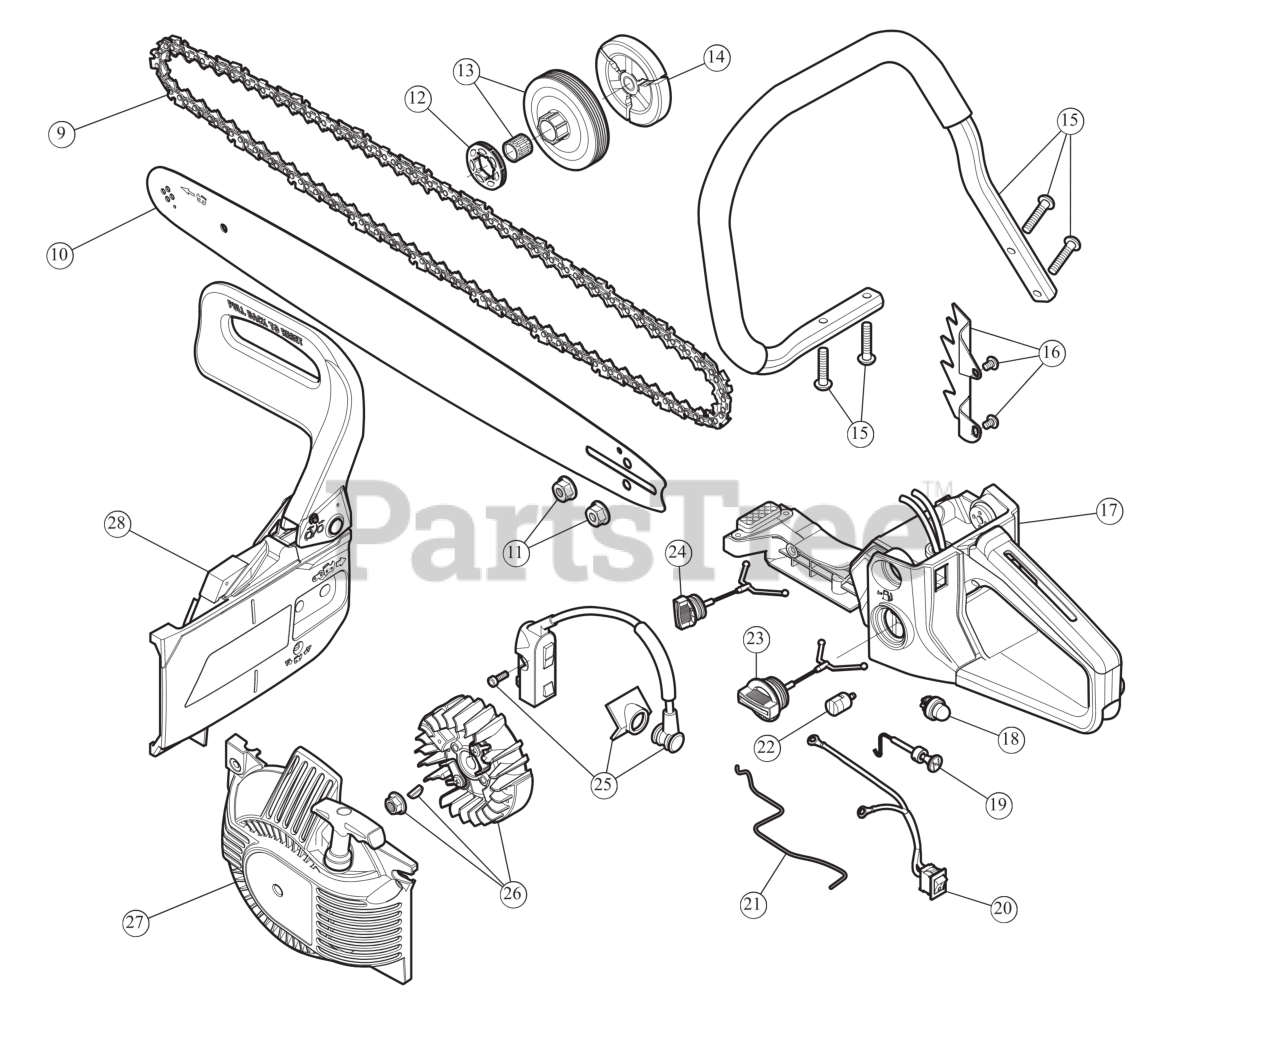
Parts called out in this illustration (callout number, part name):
9	20" CHAINSAW CHAIN
10	20" GUIDE BAR
11	BAR NUT M8
13	CLUTCH DRUM ASSEMBLY
14	CLUTCH ASSEMBLY
15	HANDLE ASSEMBLY
16	SPIKE PLATE W/HDW
17	FUEL HOUSING ASSEMBLY
18	PRIMER BULB YD2500-18410
19	CHOKE LEVER
20	SWITCH ASSEMBLY
21	THROTTLE ROD
22	FUEL FILTER YD4600-18034
23	FUEL CAP ASSEMBLY
24	OIL CAP ASSEMBLY
25	MODULE
27	STARTING HOUSING
